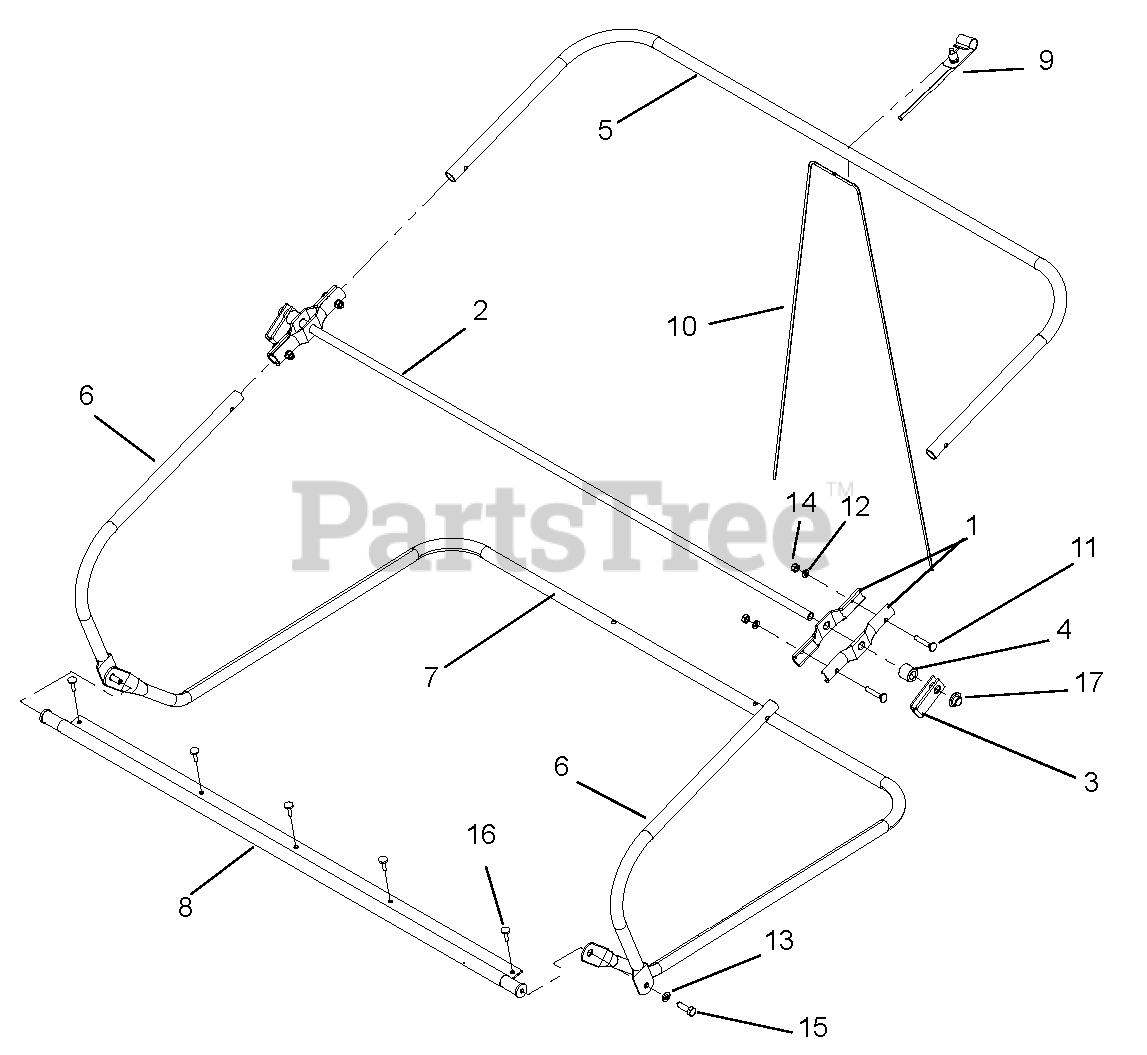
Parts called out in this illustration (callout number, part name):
1	Pivot Bearing
2	Rod, Pivot 44-3/4
3	Latch Pivot
4	Spacer, .513 x .875 x .750
5	Frame, Basket Front
6	Frame, Basket Rear
7	Frame, Basket Lower
8	Basket Clamp Assembly
9	Rope and Clip Assembly
10	Spring, Basket
11	Bolt, Contour Head 1/4-20 x 1.50
12	Washer, Lock .25 x .062 Reg YWZC
13	Washer, Lock .31 x .078 Reg YWZC
14	Nut, Hex .25-20 YWZC
15	Bolt, Hex .31-18 x 1.00 Gr 5 YWZC
16	Rivet, Bulb Tite
17	Cap, Push On 1/2
